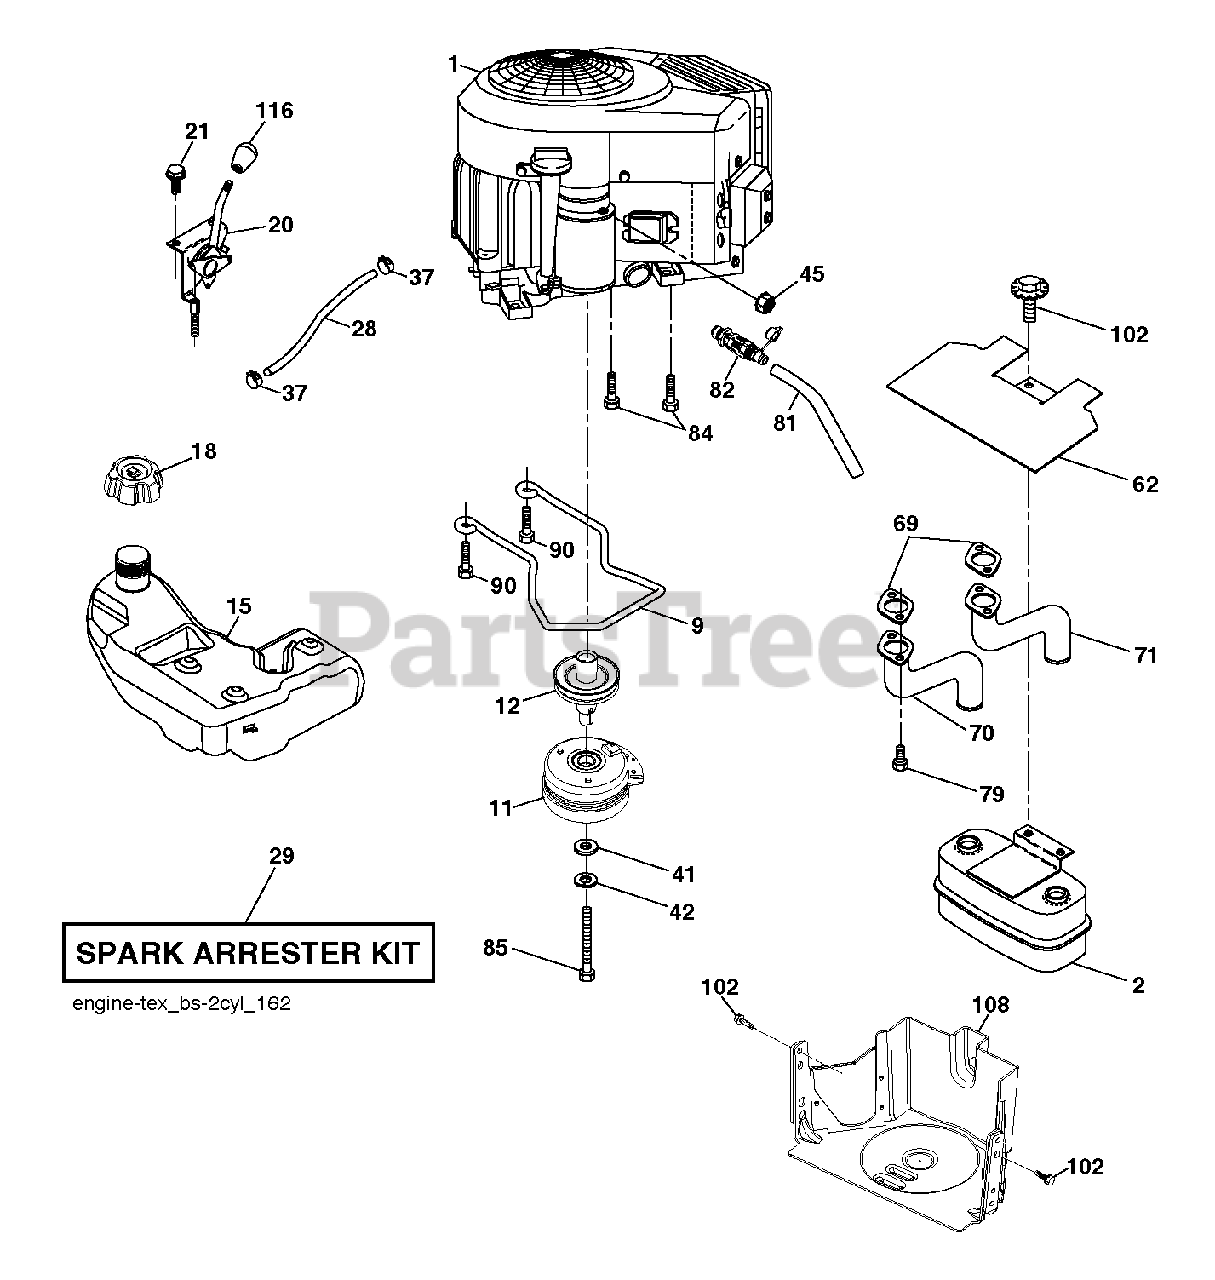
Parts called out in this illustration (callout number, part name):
2	MUFFLER.ASM.TWN.EXTNDED.DFLCTR
9	KEEPER.BELT.ENG.4.25"2.BLT.431
11	CLUTCH. 5.0 PD. 2.5 OFFSET
12	PULLEY.EXTENDED.SHAFT.GROUND
15	TANK.FUEL.4GAL
18	CAP.ASSY.FUEL.3".N-EPA.GRY.498
20	THROTTLE.PRO.RSTART. 38
21	SCREW.#10 X 0.750.BOS
28	REPL BY 532 00 85-43
29	KIT.SPARK ARRESTOR 794945 B&S
37	HOSE CLAMP
42	LOCKWASHER
45	NUT
62	SHIELD.HEAT.MUFFLER
69	GASKET.MUFFLER
70	EXHAUST.TUBE.LH.BS/TWIN
71	EXHAUST.TUBE.RH.B&S.TWIN.INTEK
79	SCREW.SOCKET.HEAD.5/16-18
81	TUBE, DRAIN OIL ASM.
82	VALUE.OIL.DRAIN
84	SCREW.3/8-16
85	BOLT.HEX.7/16-20 X 5
90	SCREW 3/8-16X1
102	SCREW
108	COVER.ENG.PULLEY.42.CLRCUT.EU
116	KNOB - SHIFT
